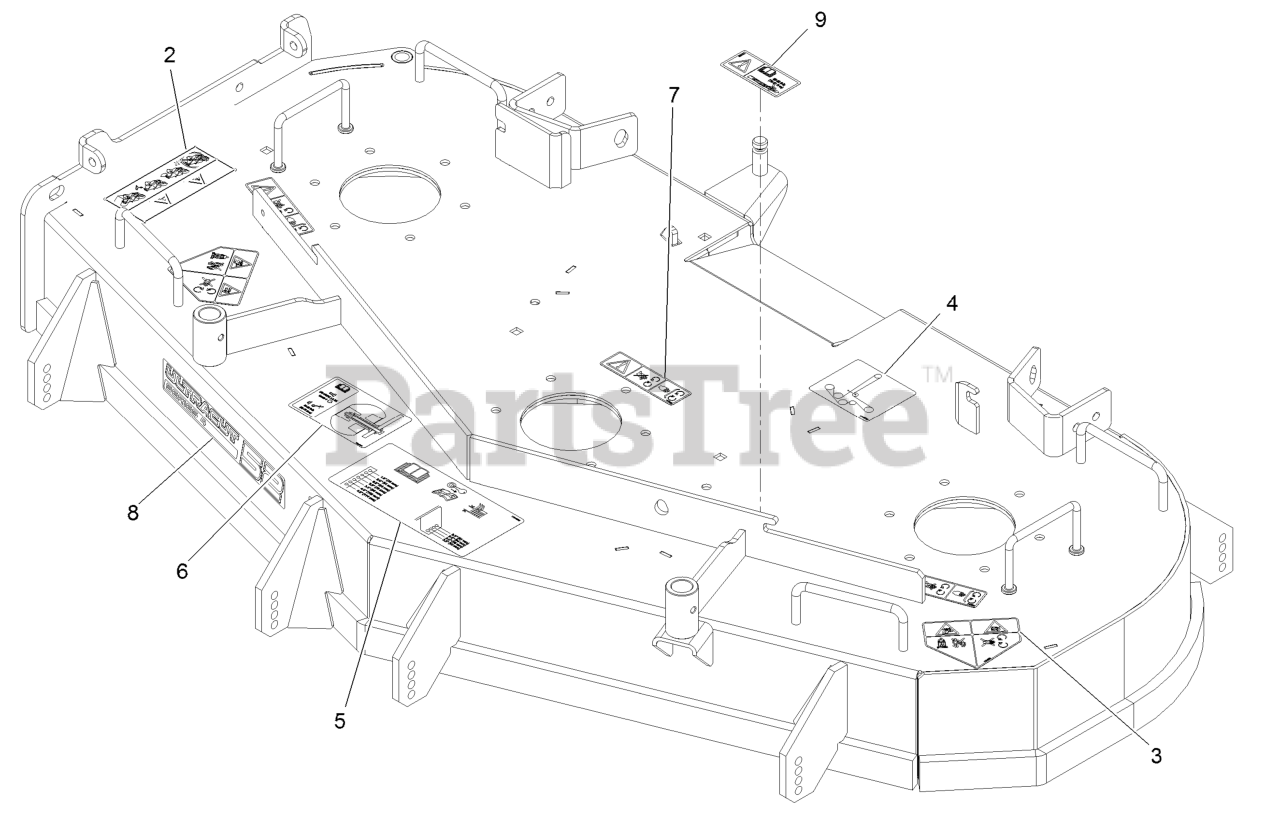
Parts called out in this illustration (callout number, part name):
2	DECAL-WARNING, BAGGER
3	DECAL-DANGER
4	DECAL-BELT ROUTING
5	DECAL-ANTI-SCALP
6	DECAL-ROLLER MOUNTING
7	DECAL-COVER, MISSING
8	DECAL, 524
9	DECAL-BOLT TORQUE
